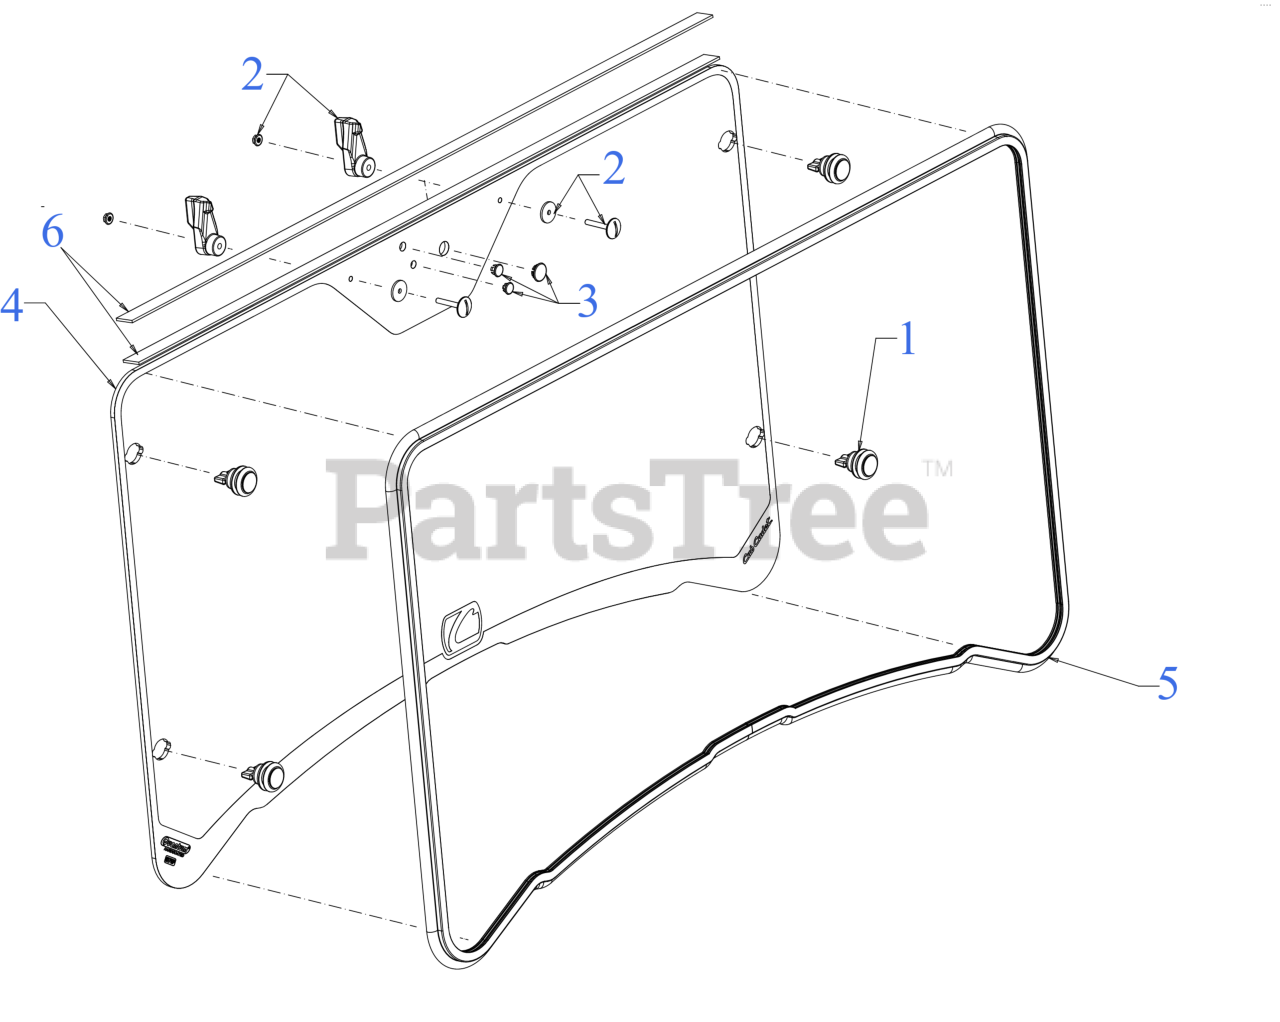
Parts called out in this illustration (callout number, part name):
1	1/4 TURN FASTENER
2	LEVER ASSEMBLY (UPPER)
3	HOLE PLUG KIT
4	WINDSHIELD PANEL
6	ADHESIVE BACKED SEAL
